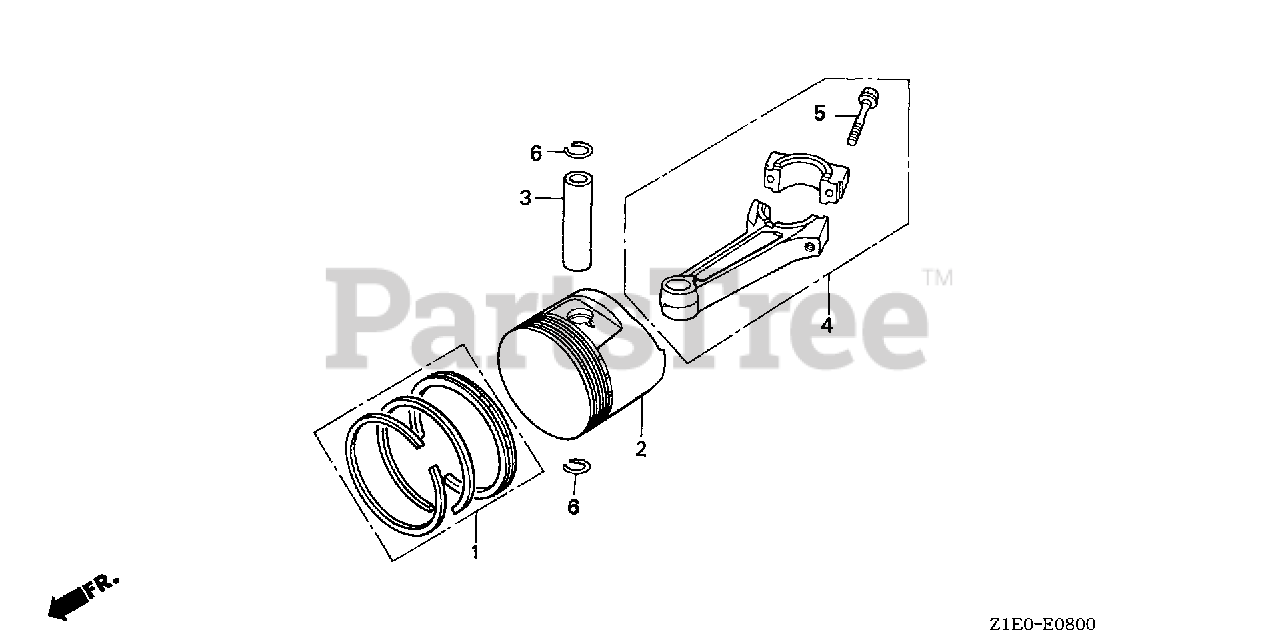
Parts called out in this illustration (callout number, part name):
1	RING SET, PISTON (STD.) (RIKEN)
1	RING SET, PISTON (STD) (TEIKOKU)
1	RING SET, PISTON (0.25) (RIKEN)
1	RING SET, PISTON (0.25) (TEIKOKU)
1	RING SET, PISTON (0.50) (RIKEN)
1	RING SET, PISTON (0.50) (TEIKOKU)
1	RING SET, PISTON (0.75) (RIKEN)
1	RING SET, PISTON (0.75) (TEIKOKU)
2	PISTON (STD)
2	PISTON (OS 0.25)
2	PISTON (0.25)
2	PISTON (OS 0.50)
2	PISTON (0.50)
2	PISTON (OS 0.75)
2	PISTON (0.75)
3	PIN, PISTON
4	ROD ASSY., CONNECTING (STD)
4	ROD ASSY., CONNECTING (0.25 LOWER SIZE)
5	BOLT, CONNECTING ROD
6	CLIP, PISTON PIN (20MM)
